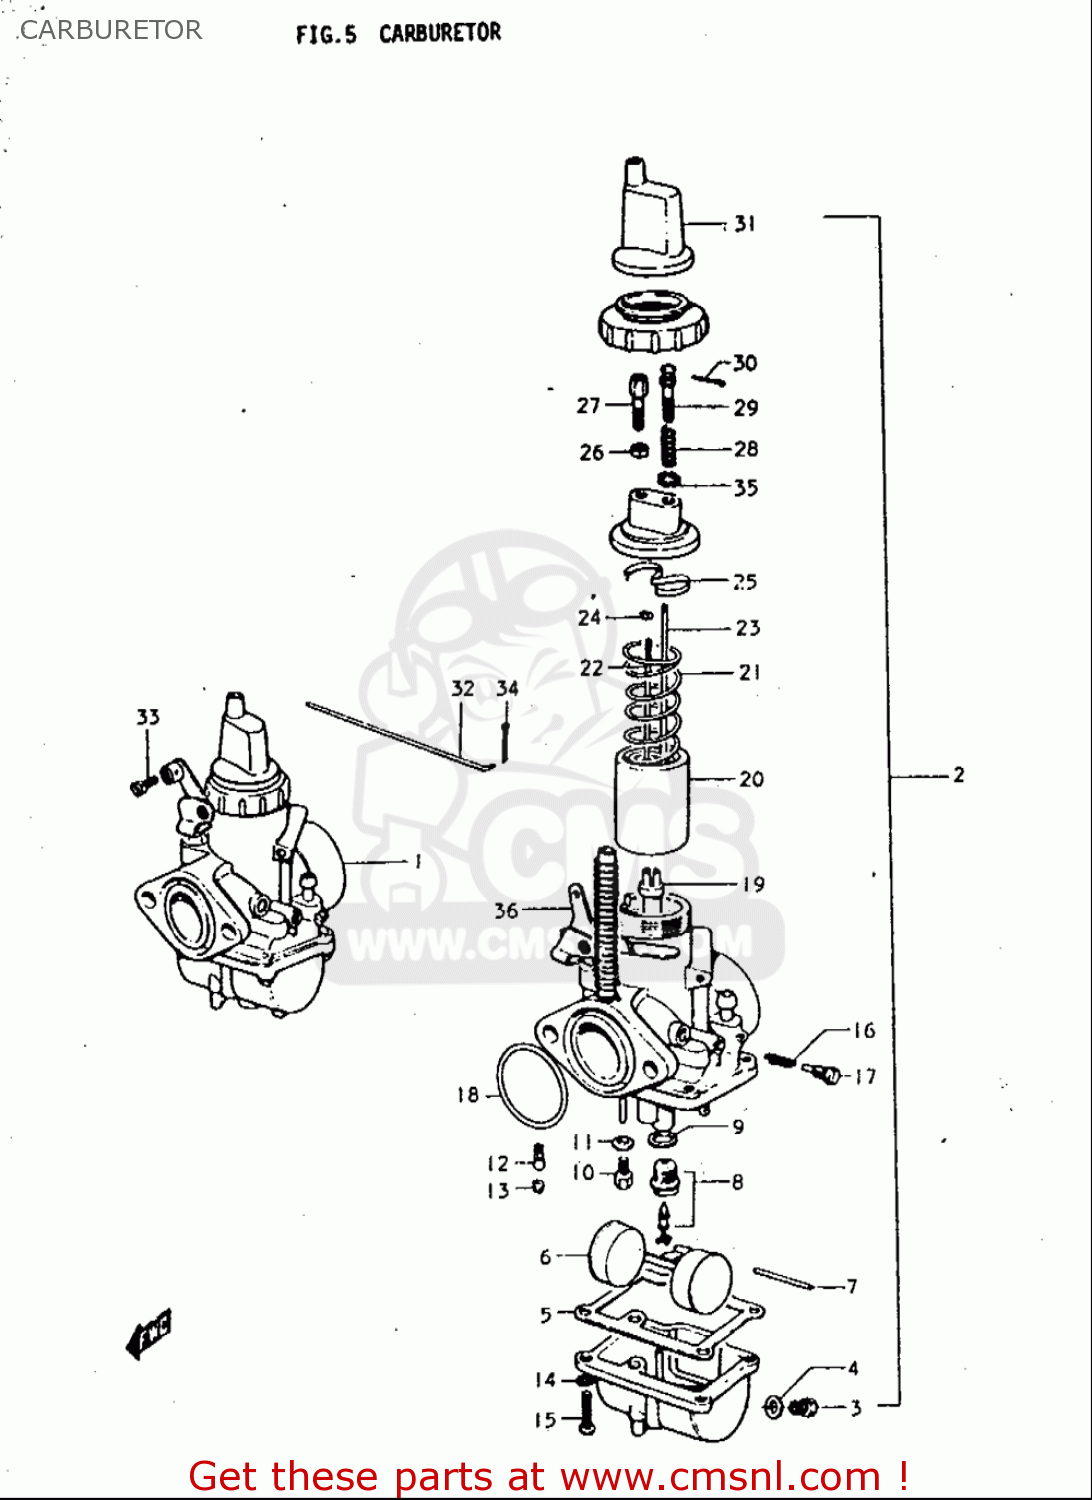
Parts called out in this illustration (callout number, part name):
3	PLUG
4	GASKET,DRAIN,PLUG (NAS)
5	GASKET,FLOAT CAHMBER (NAS)
6	FLOAT
7	PIN,FLOAT
8	VALVE ASSY,NEEDLE
9	GASKET,MAIN JET HOLDER (NAS)
10	JET,MAIN(110)
11	WASHER
12	JET,PILOT(30)
13	JET
14	WASHER,LOCK
15	SCREW 4X16
16	SPRING
17	SCREW,PILOT AIR
18	O RING(D:3.5,ID:31.7)
23	ROD,THROTTLE VALVE ADJUST
24	CLIP
26	NUT
27	ADJUSTER,CABLE
28	SPRING,THROTTLE SCREW
29	SCREW,THROTTLE VALVE ADJUST
32	ROD,STARTER LEVER
33	BOLT, STARTER ROD
35	LOCK WASHER
